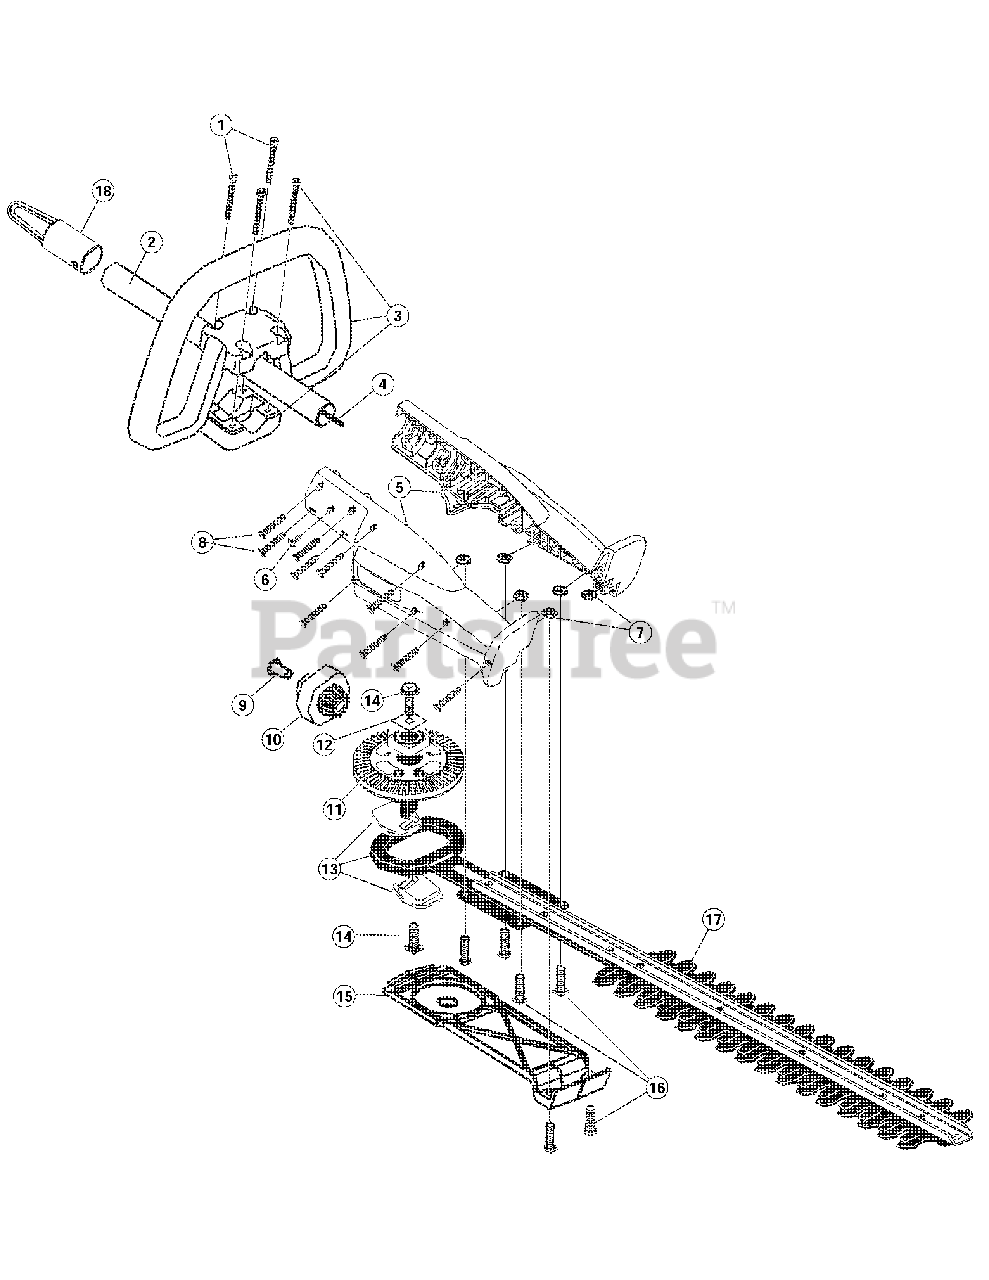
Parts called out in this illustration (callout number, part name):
2	Drive Shaft Housing Assembly
3	Loop Handle Assembly
4	Drive Shaft Assembly
5	Housing Set
6	Anti-Rotation Screw
8	Housing Screw
10	Pinion Gear
11	Bevel Gear Asm (Includes items 12-14)
13	Cam Assembly
15	Bottom Plate
17	Cutting Blade Assembly
18	Hanger
